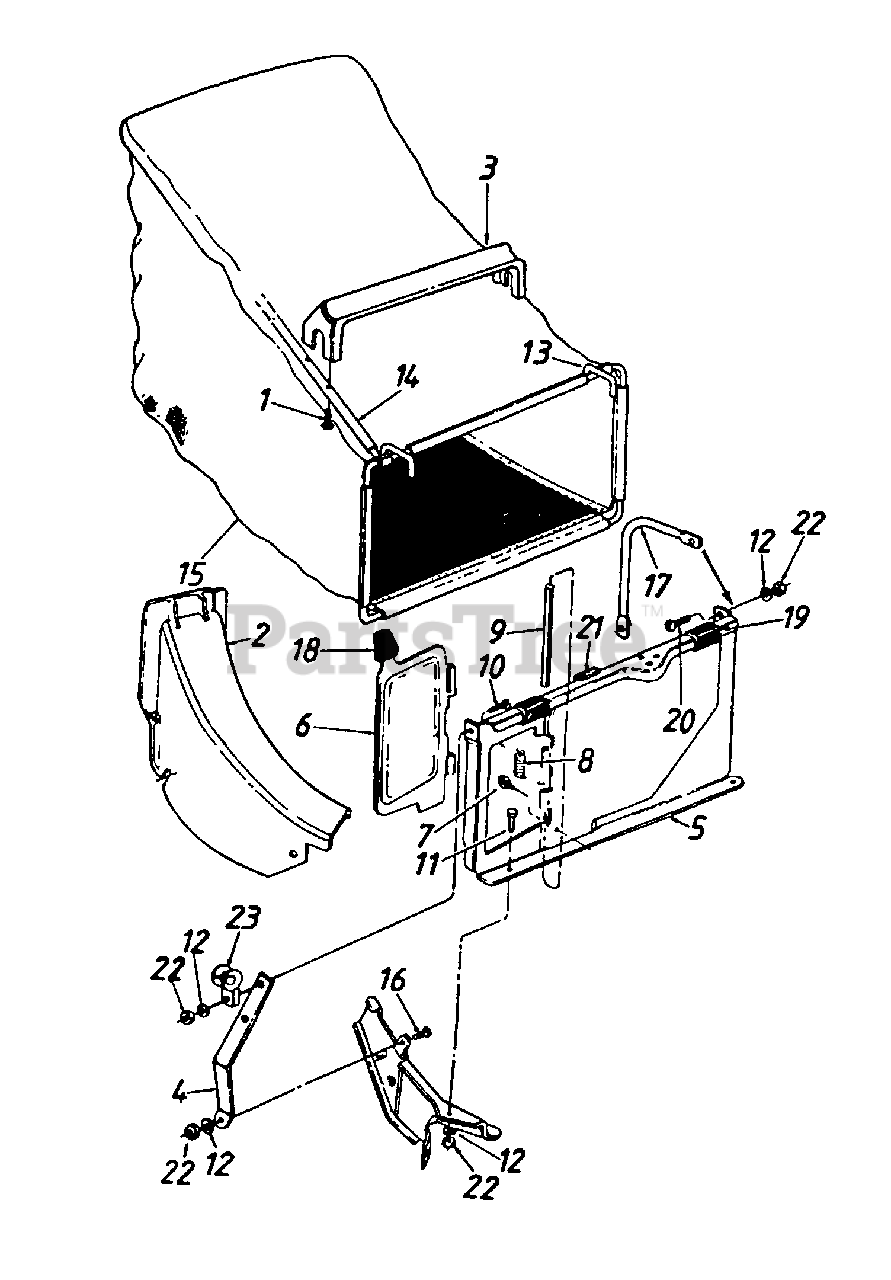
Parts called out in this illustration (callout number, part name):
1	Hex AB-Tap Scr. #12 x 1.25" Lg.
2	Rear Discharge Chute Ass'y.
3	Bag Handle
7	Hex B-Tap Scr. #10 x .38"
8	Torsion Spring
9	Pivot Pin
10	Truss Mach. Scr. 1/4-20 x 3/4" Lg.
11	Hex Bolt 1/4-20 x .50" Lg.
12	L-Wash. 1/4" I.D.
15	21" Rear Discharge Grass Bag
16	Hex Bolt 1/4-20 x .62" Lg.
17	Catcher Panel Support Arm
18	Door Grip
19	Panel Clip
20	Truss Mach. Scr. 1/4-20 x .62" Lg.
21	Foam Strip
22	Hex Nut 1/4-20 Thd.
23	Rope Guide
